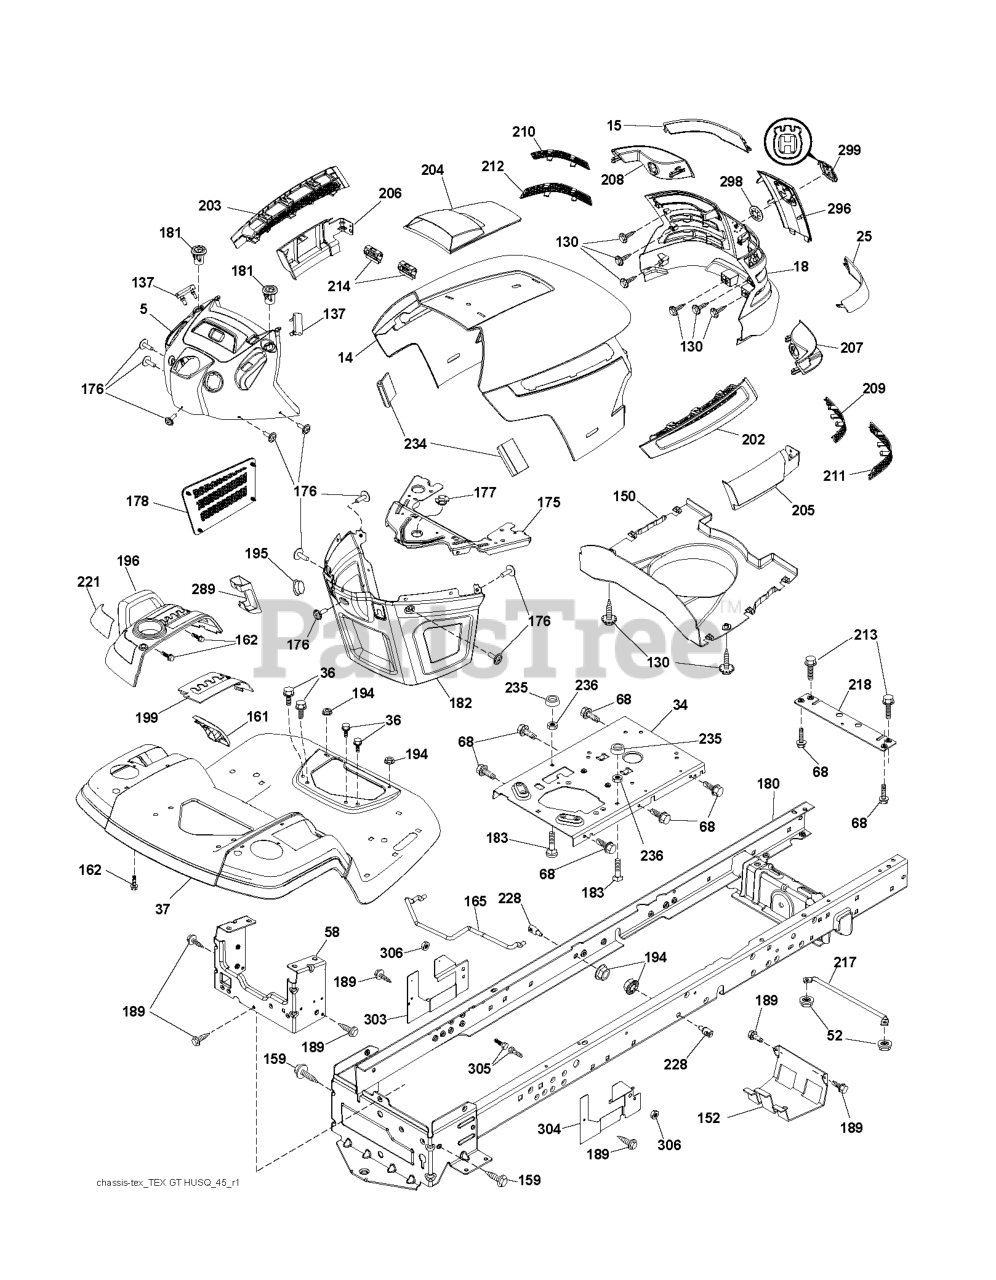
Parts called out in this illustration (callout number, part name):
14	HOOD
15	LENS.LH.TEX.GT.HUSQ.CL
18	GRILL.ASM.HUSQ.TG/CRD.W/TRIM
25	LENS.RH.TEX.GT.HUSQ.CL
34	PLATE.ENGINE.WELDED.CHASSIS
36	SCREW 5/16"
37	FENDER.PNT.TX.GT.CH/FW.ORANGE
52	LOCKNUT
58	DRAWBAR.UPPER.2PC,LRG.FENDER
68	Screw 5/16-18 x 1/2 Hex, Self Tapping 5/16-18 x 1/2
130	SCREW.#10 X 0.750.BOS
137	BUMPER DASH
150	AIR.DUCT.TEXGT.HUSQ.31
152	SHIELD.BROWNING.W/TEX
159	SCREW, 3/8-16X3/4
161	CONSOLE.FUEL.WINDOW.HU
162	SCREW.HI-LO.CONSOLE
165	SUPPORT.TANK.REAR.W/TEX
175	PLATE.CROSSMEMBER.HUSQ
176	SCREW.#10-24X5/8.RN.QU
177	BUSHING, STEERING
178	CARGO.ASM.NET.TXGT.W/C
180	CHASS.WLDMNT.TLT.12GA/2PC.20"
181	BUSHING.MNT.FEND.CRGO.
182	DASH.LOWER.COMMON.12V.ADAPTOR
183	BOLT.5/16-18X1-1/4 FULL THD
189	SCREW
194	NUT LOCK HEX FLANGE 5/16-18
195	PLUG.HOLE.DASH.LOWER.12V.BLK
196	RP CONSOLE.ASM.DECKLFT.W/
199	PLATE.DECK.LIFT.HUSQVARNA.GT
202	VENT.SIDE.HOOD.HUSQ.RH.GREY
203	VENT.SIDE.HOOD.HUSQ.LH.GRAY
204	HOOD VENT
205	SKIRT.HOOD.SIDE.HUSQ.RH.GREY
206	SKIRT.HOOD.SIDE.HUSQ.LH.GREY
207	BEZEL.RH.TEX.GT.HUSQ
208	BEZEL.LH.TEX.GT.HUSQ
209	INSERT.HEX.GRILL.HUSQ.GREY
210	INSERT.HEX.GRILL.HUSQ.
211	INSERT.HEX.GRILL.HUSQ.
212	INSERT.HEX.GRILL.HUSQ.
213	BOLT
214	CLIP.RETAINER.TINNER.
217	ROD.PIVOT.HOOD
218	X-PIECE.HOOD.STOP.NON/
221	REFLECTOR.LH.TEX GT HU
228	STUD.FASTNER.W/ANTI-ROTATE
234	BUMPER.HOOD.TEX.HUSQVARNA
235	SPACER FENDER
236	NUT.CENTERLOCK.5/16-
289	PLUG.N/CRUISE.COMMON.YT/GT.BLK
296	TRIM.HUSQ.TG/CRD.SERVICE
298	NUT PUSH M
299	RP LOGO
303	SHIELD CHASSIS LEFT
304	SHIELD CHASSIS RIGHT
306	NUT LOCK FLG 3/8-16 UNC
